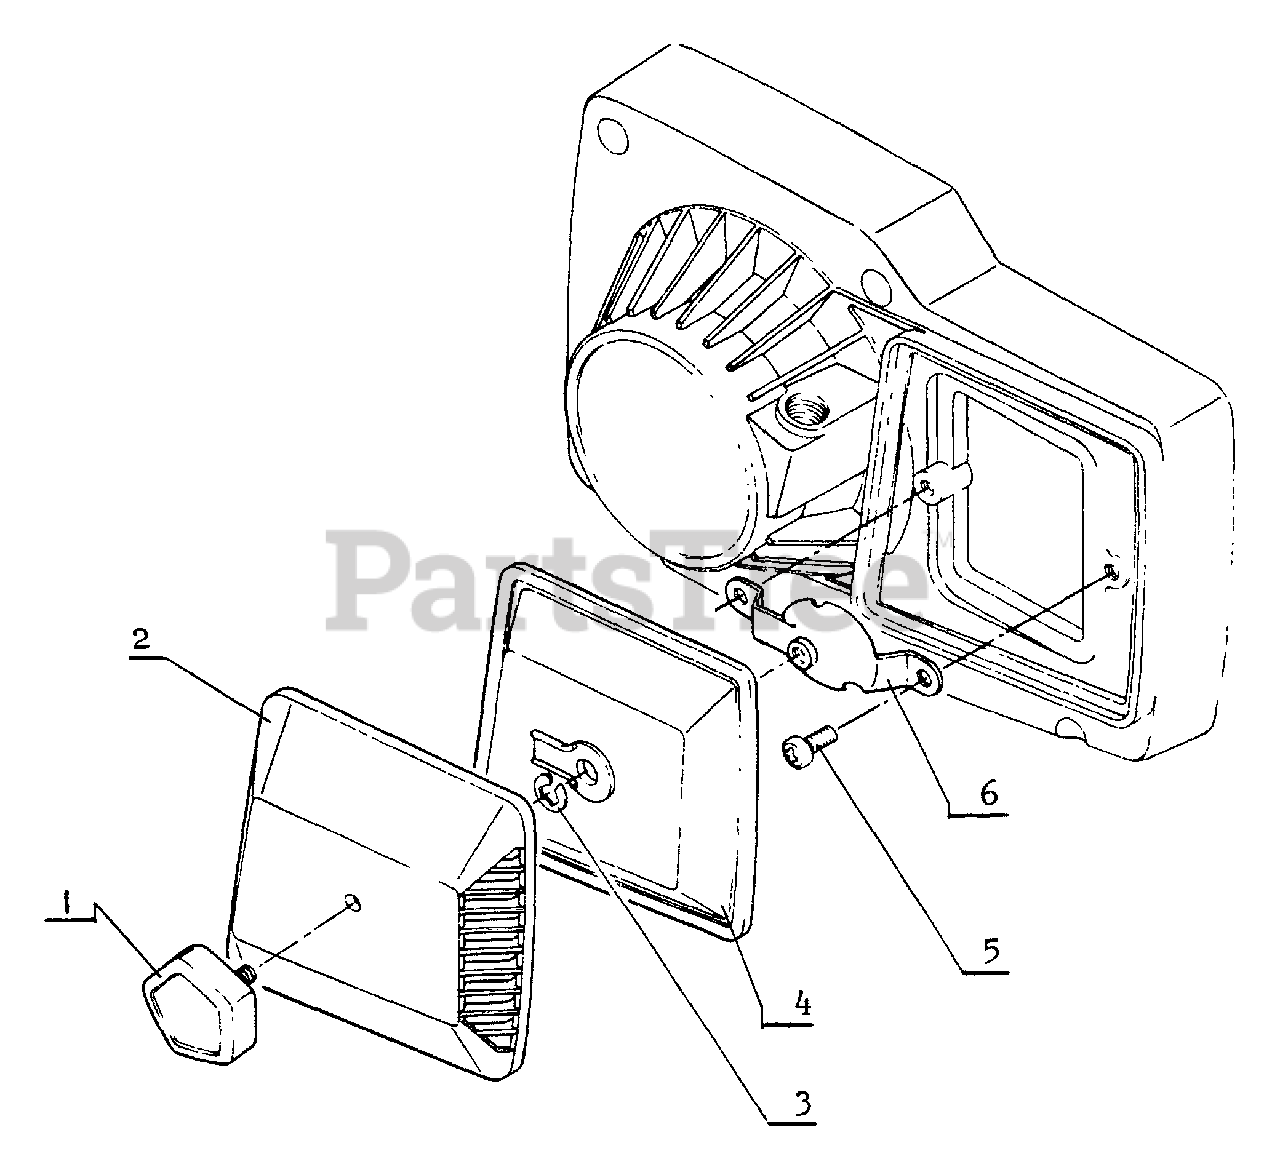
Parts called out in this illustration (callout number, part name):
1	THUMBSCREW
2	COVER, AIR FILTER
3	E-RING 4
4	FILTER, AIR
5	SCREW 5×10
6	PLATE, PREVENT
